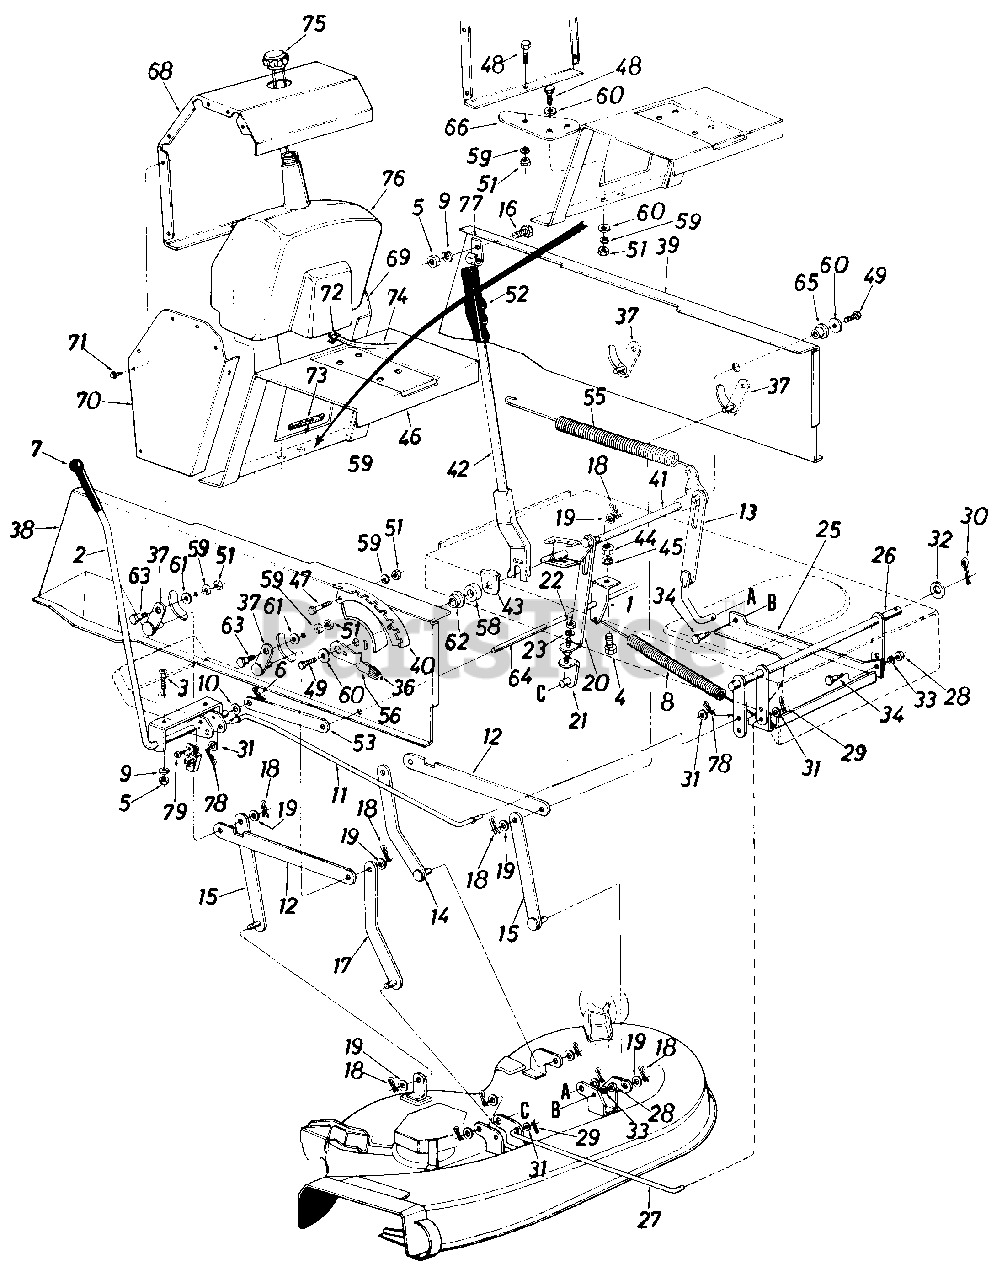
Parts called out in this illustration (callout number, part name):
1	Spring Hanger Bracket
2	Deck Engagement Lever Ass'y.
3	Truss Mach. Scr. 5/16-18 x .75' Lg.
4	Hex Bolt 1/4-20 x .62" Lg.
5	Hex Nut 5/16-18 Thd.
6	Cotter Pin 3/32" Dia. x 1.00" Lg.
8	Ext. Spring .99" O.D. x 13.25" Lg.
9	L-Wash 5/16" I.D.
10	Fl-Wash 10' I.D. x 1.0" OD
11	Drive Deck Control Rod
12	Connecting Rod 3/16 x 1 x 1 2.5
13	Deck Lift Link Ass'y.
14	Deck Hanger Link Ass'y. Rear L.H.
15	Deck Hanger Link Ass'y.
16	Hex Bolt 5/16-18 x .75" Lg.
17	Deck Hanger Link Ass'y. Front R.H.
18	Inter. Cotter Pin 1/2" Dia.
19	Fl-Wash. .531 I.D. x .93" O.D.
20	Adj. Link Deck Lifting
21	Adj. Lower Link Ass'y.
22	Hex Jam Nut 3/8-16 Thd.
23	L-Wash. 3/8 I.D.
25	Diagonal Brace
26	Stabilizer Shaft Ass'y.
27	Stabilizer Rod
28	Hex Nut 3/8-16 Thd.
29	Inter. Cotter Pin 5/16" Dia.
30	Cotter Pin 1/8" Dia. x 1.25" Lg.
31	Fl-Wash. .385" I.D. x .620" O.D.
32	Fl-Wash. .635" I.D. x 1.12" O.D.
33	L-Wash. 3/8" I.D.
34	Shoulder Bolt 3/8-16
36	Knob Height Adj.
37	Pivot Link Ass'y.
38	Side Panel Upper Frame R.H.
39	Side Panel Upper Frame L.H.
40	Index Brk't.
43	Retainer Wash. Lift Handle
44	Hex Nut 1/4-20 Thd.
45	L-Wash. 1/4" I.D.
46	Hitch Plate
48	Hex Bolt 5/16-18 x 1.00" Lg. Grade 5
49	Hex Wash. TT-Tap Scr. 5/16-18 x .62" Lg.
51	Hex Nut 5/16-18 Thd.
52	Grip
53	Link 1.0" x 7.5" x .19
55	Ext. Spring .99" Dia. x 1 1.00" Lg.
56	Deck Lift Down Stop
58	Rubber Wash. 1-1/2" O.D. x .63" I.D. x .6 Lg.
59	L-Wash. 5/16" I.D.
60	Fl-Wash. .344" I.D. x 1.125" O.D. x .125
61	Fl-Wash. .344" I.D. x .62" O.D. x .063
62	Flange Wash. .628" I.D. x 1.25" O.D.
63	Shld. Bolt .437" Dia. x .180
64	Running Board Rod
65	Flange Brg. .632" I.D.
66	Hitch Bar
68	Gas Tank Housing Main Panel
69	Side Panel L.H. Gas Tank
70	Side Panel R.H. Gas Tank
71	Truss Mach. B-Tapp Scr. #10 x .50" Lg.
72	Hose Clamp .406" Dia.
73	Trim Strip 5" Lg.
74	Gas Line 44" Lg.
75	Gas Tank Cap
76	Gas Tank
77	Hose Clamp
78	Cotter Pin 3/32" Dia. x .75" Lg.
79	Hex Wash. Hd. Tap Scr. 1/4 x .50" Lg.
